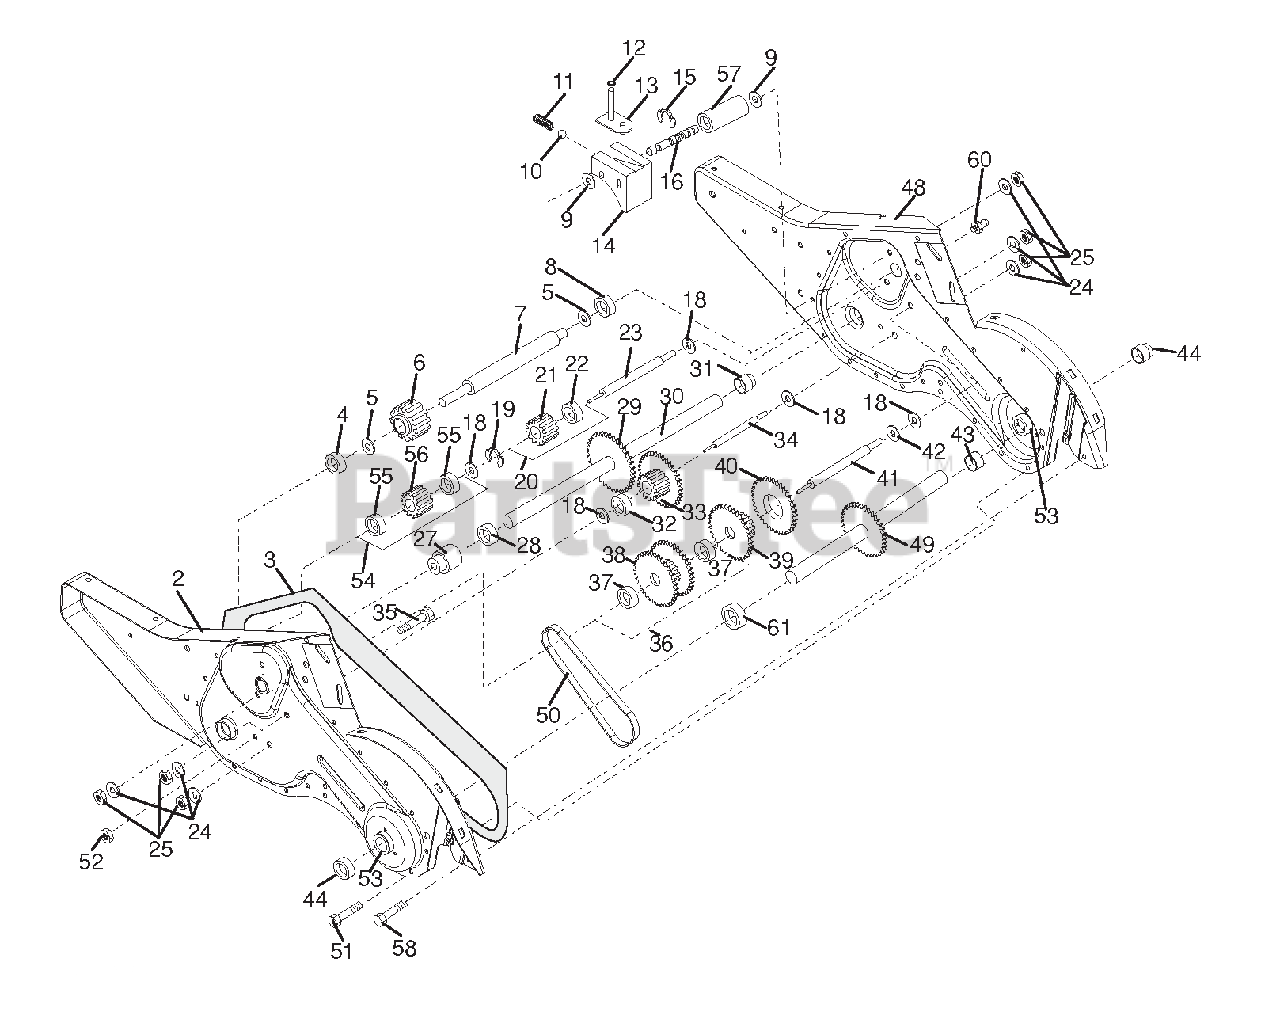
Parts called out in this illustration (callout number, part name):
1	Transmission Assembly (Include
2	Gearcase, LH w/Bearing (Includ
3	GASKET, GEARGASE
4	Bearing, Needle
5	Washer, Thrust 5/8 x 1.10 x 1/
6	Pinion, Input
7	Shaft, Input
8	Bearing, Needle
9	Washer, Seal
10	Ball, Steel
11	Spring, Shift, Fork
13	Arm, Shift
14	Fork, Shift
15	Ring, Klip
16	Shaft, Shift
19	Ring, Klip
20	Gear, Assembly, Reverse Idler
21	Gear, Reverse Idler
22	Bearing, Needle
23	Shaft, Reverse Idler
24	WASHER.LOCK.HVY HLCL.SPR.7/16
25	Nut, Hex 7/16-20
27	Bearing, Shaft, Ground Drive L
28	Spacer 0.765 x 1.125 x 1.23
29	Chain #35-50 Pitch
30	Ground Shaft Assembly
31	Bearing, Shaft, Ground Drive R
32	Spacer 0.70 x 1.00 x 1.150
33	Sprocket and Gear Assembly
34	Shaft, Reduction (2nd)
35	Screw, Whiz, Lock 5/16-18 x 3-
36	Sprocket Assembly w/Bearing (I
37	Bearing, Needle
38	Sprocket, Tine
39	Gear, Cluster, Red 1st & 2nd
40	Gear, Reverse
41	Shaft, Reduction (1st)
42	Washer, Thrust
43	Spacer 1.01 x 1.75 x 0.760
44	Seal Asm. Oil
48	Gearcase, RH w/Bearing (Includ
49	SHAFT, TINE
50	Chain, Roller #50-50 Pitch
51	Screw 1/4-20 x 1/2
52	Nut, Hex 5/16-18
53	Bearing Kit, Tine Shaft
54	Gear, DRT Idler w/Bearing (Inc
55	Bearing, Needle
56	Gear, DRT Idler
57	Spacer, Split .52 x .64 x 1.04
58	Screw 1/4-20 x .875
60	Fitting Grease
61	SPACER 1.015 X 1.50 X .650
